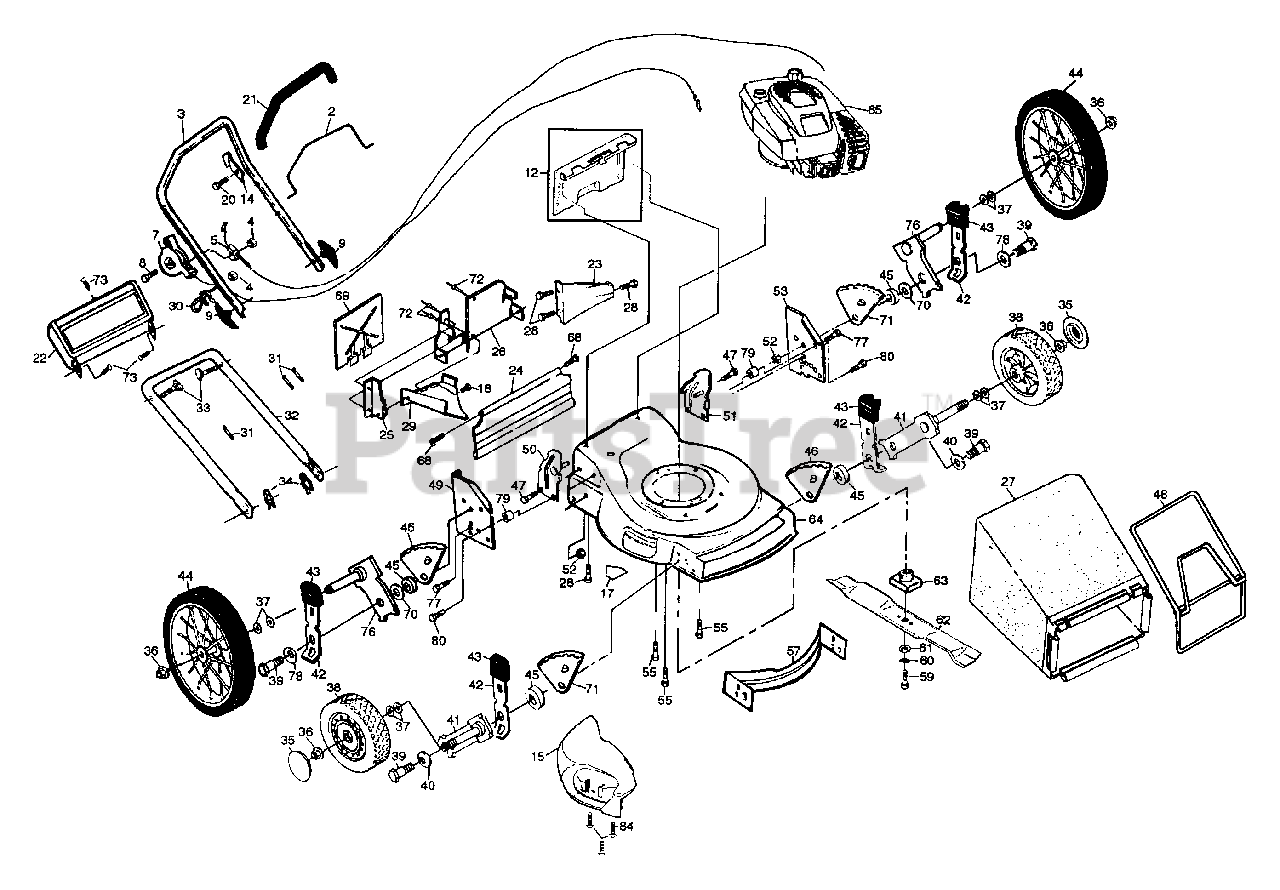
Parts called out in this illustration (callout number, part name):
2	Control Bar
3	Upper Handle
4	Locknut
5	Engine Zone Control Cable
7	Throttle Control
8	Hex Washer Head Screw 1/4-20 x 2-1/8
9	Handle Knob
12	Rear Door Kit
14	Upstop Bracket
15	Quick Trim Door
17	Danger Decal
20	Hex Washer Head Screw #10-24
21	Handle Grip
22	Trim Plate
23	Rear Baffle
24	Rear Skirt
25	Side Baffle
26	Back Plate
27	Grass Bag
28	Screw Hex Head 1/4-20 x 1/2
29	Discharge Baffle
30	Rope Guide
31	Wire Ties
32	Lower Handle
33	Handle Bolt
34	Hairpin Cotter
36	Flanged Locknut
37	Wave Washer
38	Wheel & Tire Assembly (Front)
39	Shoulder Bolt
40	Belleville Washer
41	Axle Arm
42	Selector Spring
43	Selector Knob
44	Wheel & Tire Assembly (Rear)
45	Spacer
46	Wheel Adjusting Bracket R.R.
47	Self-tapping Screw 5/16-18 x 3/4
48	Catcher Frame
49	Wheel Support Bracket (Right)
50	Handle Bracket (Right)
51	Handle Bracket (Left)
52	Locknut 3/8-16
53	Wheel Support Bracket (Left)
55	Hex Head Thread Rolling Screw 3/8-16 x 1
57	Front Baffle
59	Hex Head Machine Screw 3/8-24 x 1-3/8 Gr. 8
60	Helical Lock Washer
61	Hardened Washer
63	Blade Adapter
64	Lawn Mower Housing Kit
65	Engine - Tecumseh
68	Hinge Screw
69	Mulcher Plate
70	Flat Washer
71	Wheel Adjusting Bracket L.R.
73	Push-in Fastener
76	Axle Arm Assembly
78	Spacer
